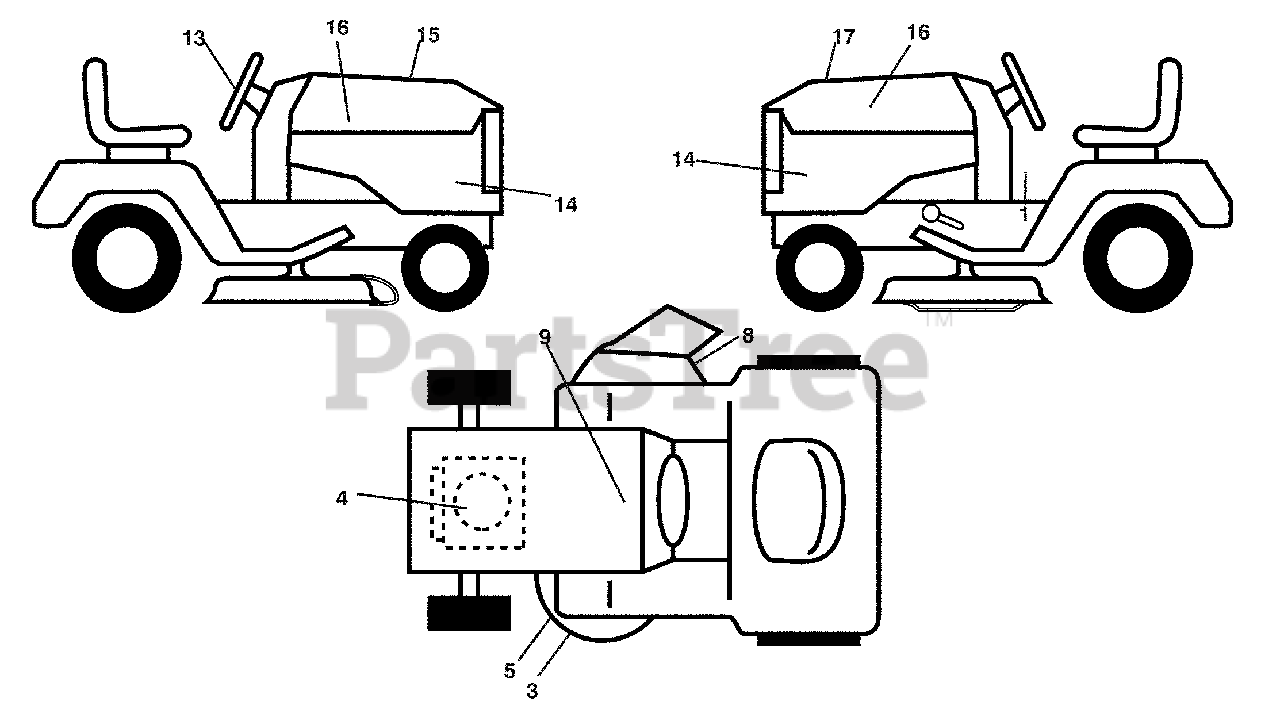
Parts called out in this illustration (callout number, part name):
1	Decal, Warning
3	Decal, Warning
4	Decal, Engine HP
5	Decal, Mower Caution
8	Decal, Mower Sch.
9	Decal, Battery Dnge/Poi
13	Decal, Steering Whl
14	Decal, Panel Side
15	Decal, Cust. Resp.
16	Decal, Hood Logo
17	Decal, Replacement
